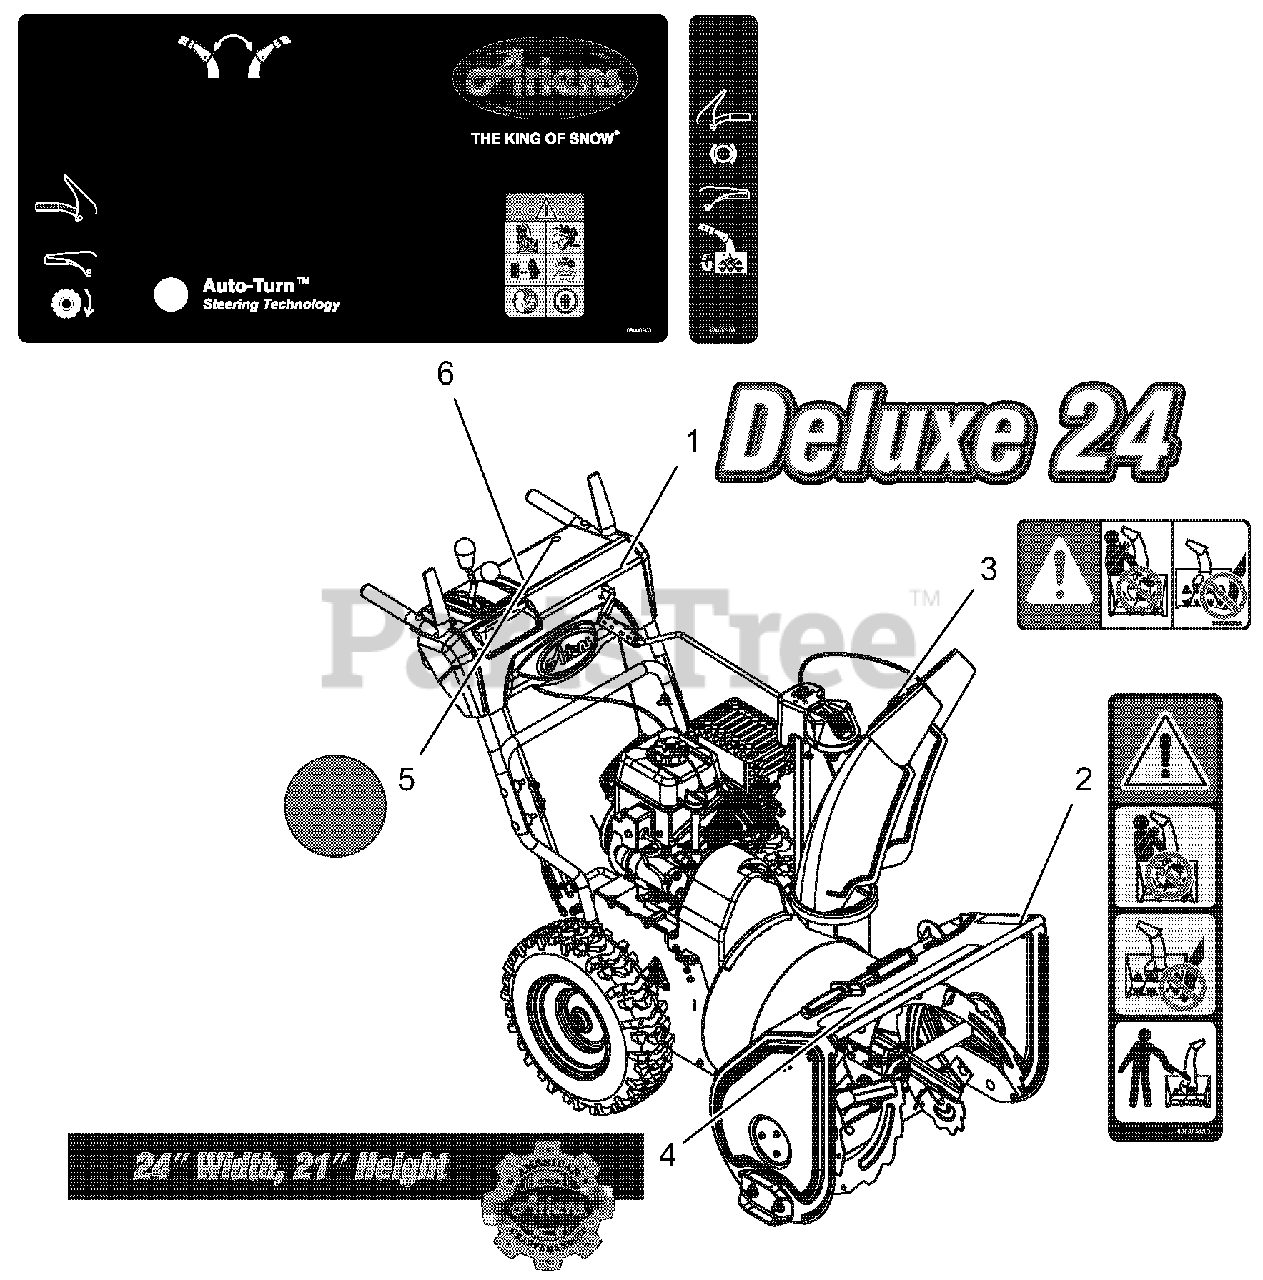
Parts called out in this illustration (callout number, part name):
1	DECAL,ST24 DELUXE-COMPACT DASH
2	DECAL, DANGER - ROTATING PARTS
3	DECAL, DANGER
5	DECAL,AUTODIFFERENTIAL
6	DECAL, CONTROL PANEL
